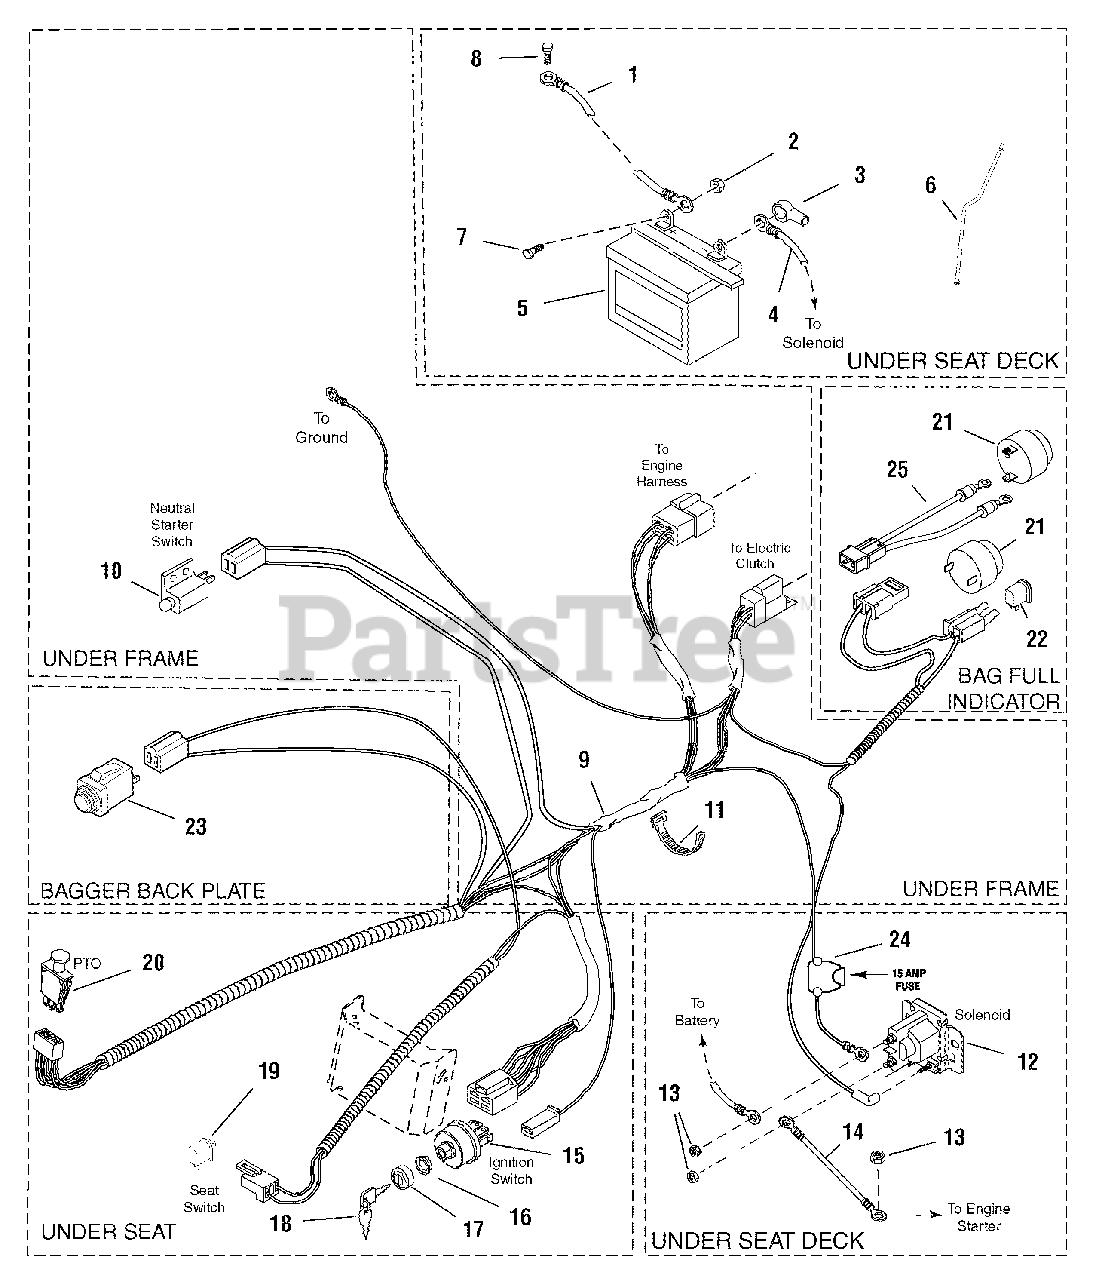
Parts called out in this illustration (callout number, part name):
1	BATTERY CABLE, Negative
2	WINGNUT, 1/4-20
3	BOOT, Battery, Positive
4	BATTERY CABLE, Positive
6	ROD, Battery
7	Bolt, Carriage 1/4-20 x .63
8	SCREW, 1/4-14 x 3/8
9	WIRE HARNESS
10	SWITCH, Limit
11	TIE STRAP
12	SOLENOID, 3 Pole
13	NUT, Nylock 1/4-20
14	CABLE, Battery 8GA 18.00L - Red
15	SWITCH, Ignition
16	NUT, Ignition Switch
17	CAP, Ignition Switch
18	KEYS, With Plasic Cover
19	SWITCH, Seat
20	SWITCH, PTO
21	BUZZER, Bag Full Indicator
22	SWITCH, BAG FULL
23	BAGGER SWITCH
24	FUSE, 15 Amp
25	HARNESS, Buzzer Connector
26	SERVICE KIT, Buzzer and Harness
